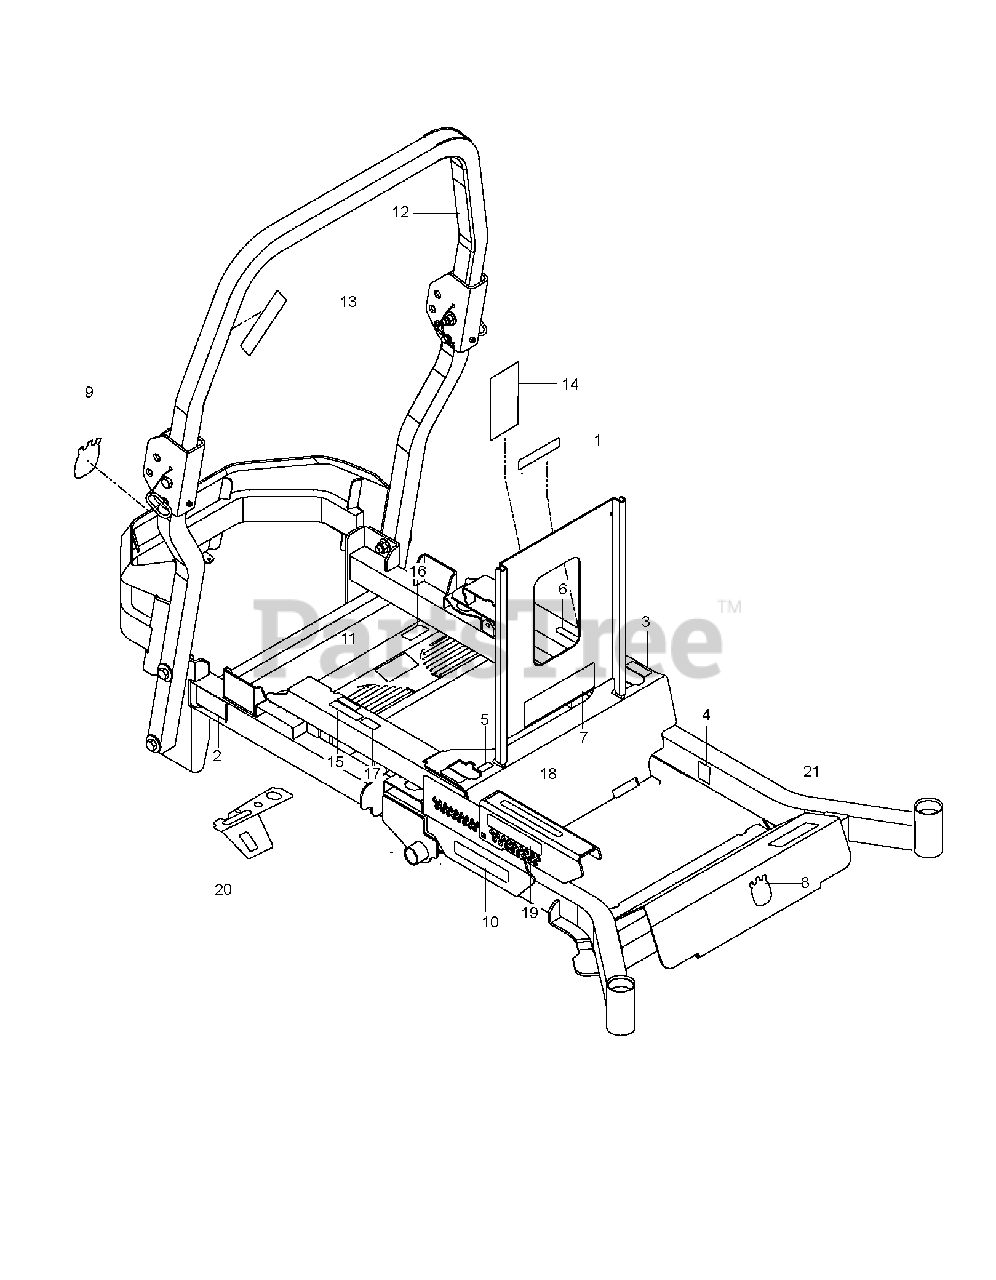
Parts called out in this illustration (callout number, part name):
1	EURO DECAL-BATTERY WARNIN6
2	DECAL, BELT DRIVE
3	DECAL.ZTR.MOTCONTRL.SYMBOL.HUS
4	DECAL.80.DBA.AUSTRALIA
5	DECAL.STR.S.T.SYSMBOLONLY.2014
6	DECAL.ZTR.PARKBRAK.SYMBOL.2014
7	DECAL.ZTR.WARNING.SMARTIGNITIN
8	DECAL.AUGER.HUSQ.CROWN.SNOW
9	DECAL, CROWN H, 110MM
10	RP.DECAL.BADGE.170MM.TEXTLOGO
11	DECAL, FUSE
12	DECAL, ROPS
13	DECAL, ROPS, WARNING
14	DECAL, SERVICE
15	DECAL, WARNING SPARK ARRESTOR
16	DECAL, FUEL
17	DECAL.80.DBA.AUSTRALIA
18	DECAL, HEIGHT
19	DECAL, HEIGHT
20	DECAL.80.DBA.AUSTRALIA
21	DECAL.PZ29
